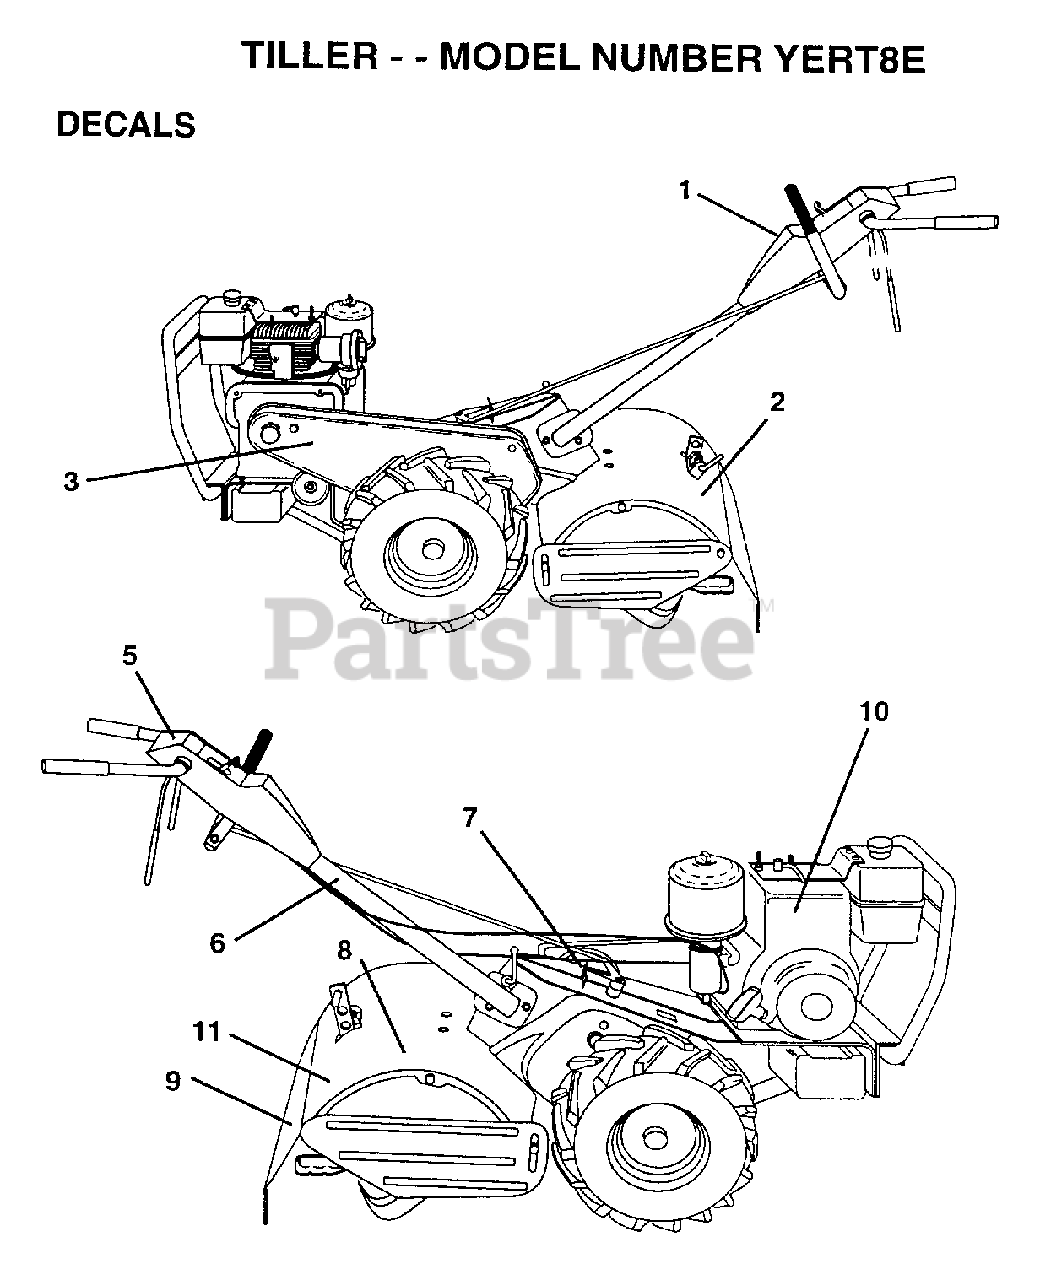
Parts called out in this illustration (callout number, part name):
1	DECAL.PNL.CONTROL
2	DECAL SHIELD TINE
3	DECAL LOGO GUARD
5	DECAL INST PNL 21
6	DECAL TI
7	DECAL INDICT SHIF
8	DECAL TI
10	DECAL, BRIGGS & STRATTON
11	DECAL.EURO.ST.CE.
